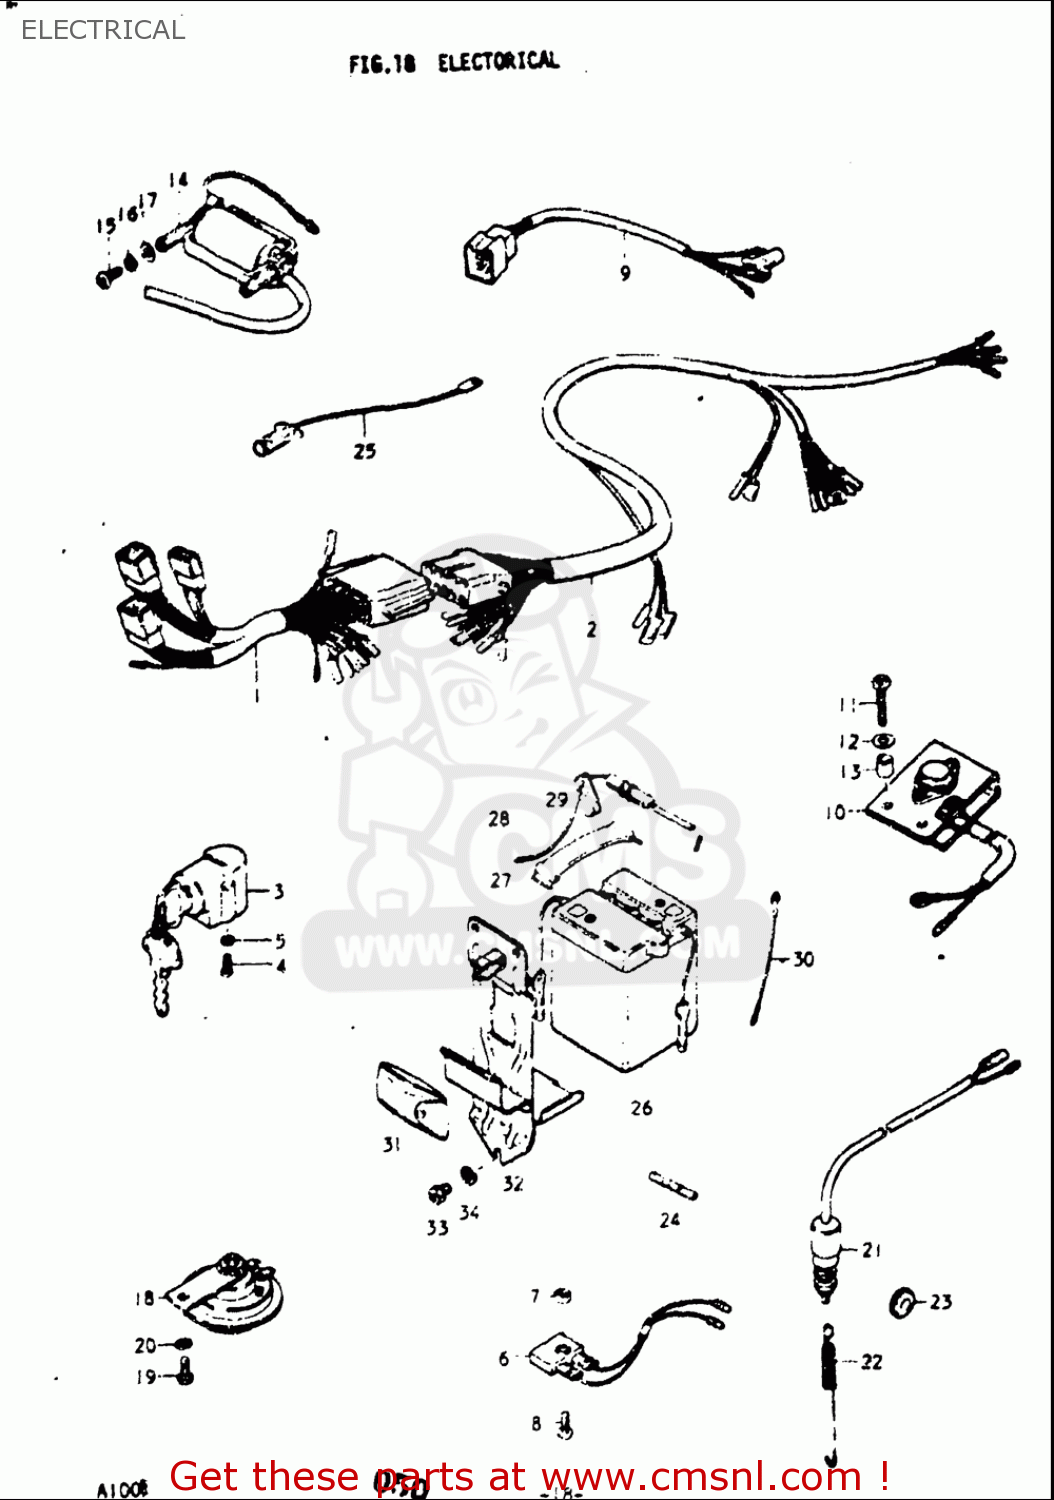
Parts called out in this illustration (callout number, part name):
4	SCREW
5	LOCK,WASHER
6	RECTIFIER ASSY
8	SCREW
10	REGULATOR ASSEMBLY
11	SCREW
12	WASHER
13	SPACER(6.5X10.5X15)
15	SCREW
16	WASHER,LOCK
17	WASHER
18	HORN ASSY
19	BOLT
20	WASHER,LOCK
21	SWITCH ASSY,STOP LAMP
22	SPRING
24	CONNECTOR
26	BATTERY ASSY(6N4-2A4.2AH)
27	BAND
28	CASE ASSY,FUSE
29	FUSE(15A)
30	LEAD WIRE
31	TOOL ASSY
32	HOLDER,BATTERY
33	SCREW(6X10)
34	WASHER,LOCK
